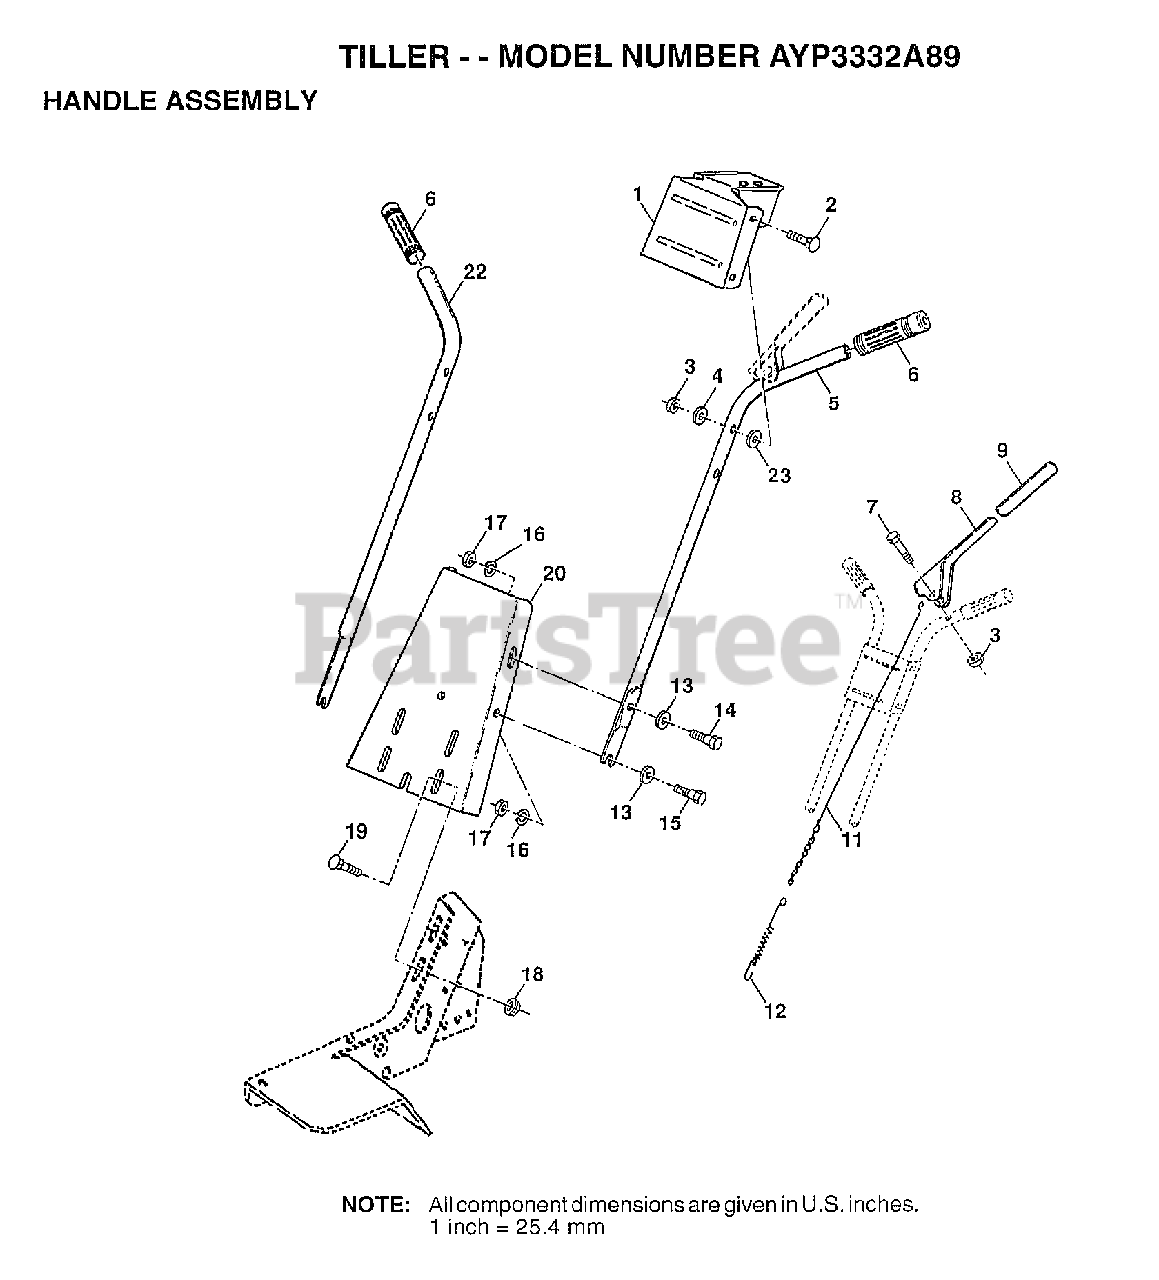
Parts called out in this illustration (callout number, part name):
1	HANDLE BRKT
2	BOLT
4	WASHER
5	HANDLE LH
7	BOLT.HEX.5/16-1.5
9	GRIP T
12	SPRING EXT TI
13	WASHER
15	BOLT
16	LOCKWASHER
17	NUT.HEX.5/16-18
18	NUT
19	BOLT
20	PANEL. HANDLE
22	HANDLE RH
23	WASHER
